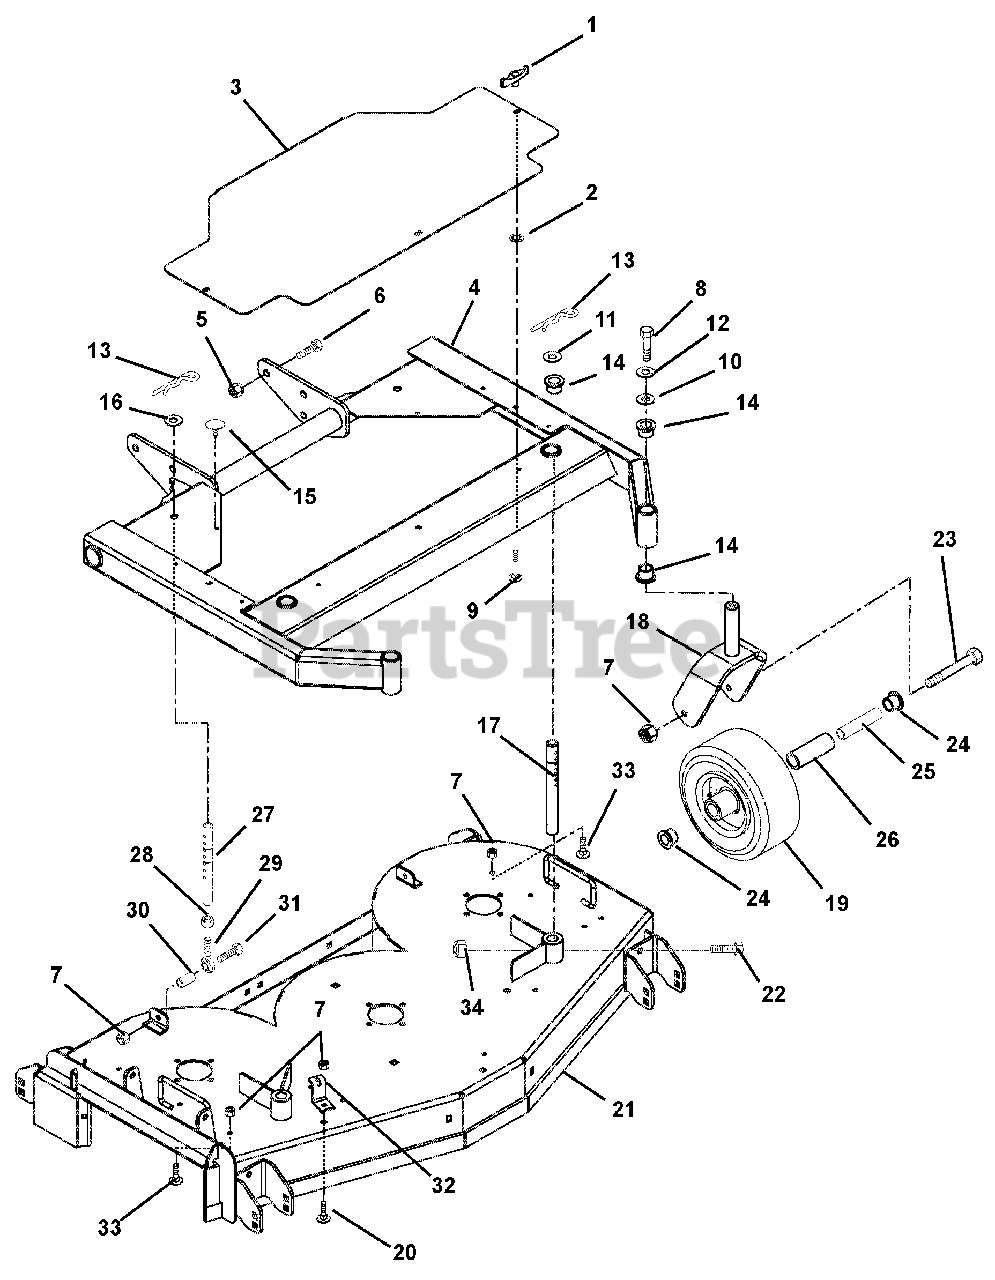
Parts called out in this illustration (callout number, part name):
1	Knob- Wing .312-18
2	Nut-Push .312
3	Cover, Belt Pro Mower
4	Weldment-Mower Frame 48" Floating (108)
5	Nut-Locking-Nylon .625-11
6	Bolt-Hex .62-11 x 1.50
7	Nut-Locking-Top-Flange .38-16
8	Bolt-Hex .38-16 x 1.25 Grade 5
9	Bolt-Round Head Square Neck .31-18 x 1.00
10	Washer-Flat-Steel .38 x 1.50 x .125
11	Washer-Flat-Steel .875 x 1.50 x .120
12	Washer-Locking .38 x .094 Regular
13	Pin-Hair-Internal .17 x .68 x 3.50
14	Bushing-Flange 1.00 x 1.25 x 1.50 x 1.50
15	Bumper Grommet .125 x .25 Dia.
16	Washer-Flat-Steel .688 x 1.75 x .134
17	Rod- Front Height Adjustment
18	Weldment-Caster Fork
19	Wheel 9 x 3.50
20	Bolt-Round Head Square Neck .38-16 x 1.00 Grade 5
21	Kit, 48" Floating Mower Deck with Decals (108)
22	Bolt-Hex .25-20 x 2.00 Grade 8
23	Bolt-Hex .38-16 x 5.50
24	Bearing-Retainer
25	Bearing .625 x .380 x 4.08
26	Bearing-Roller
27	Rod- Rear Height Adjustment
28	Nut-Jam .375-24
29	Rod End, .38 Right Hand
30	Bushing-Sleeve .377 x .624 x .37
31	Bolt-Hex .38-16 x 1.50 Grade 5
32	Anchor, Spring
33	Bolt-Round Head Square Neck .38-16 x .75 Grade 5
34	Nut-Locking-Top-Flange .25-20
